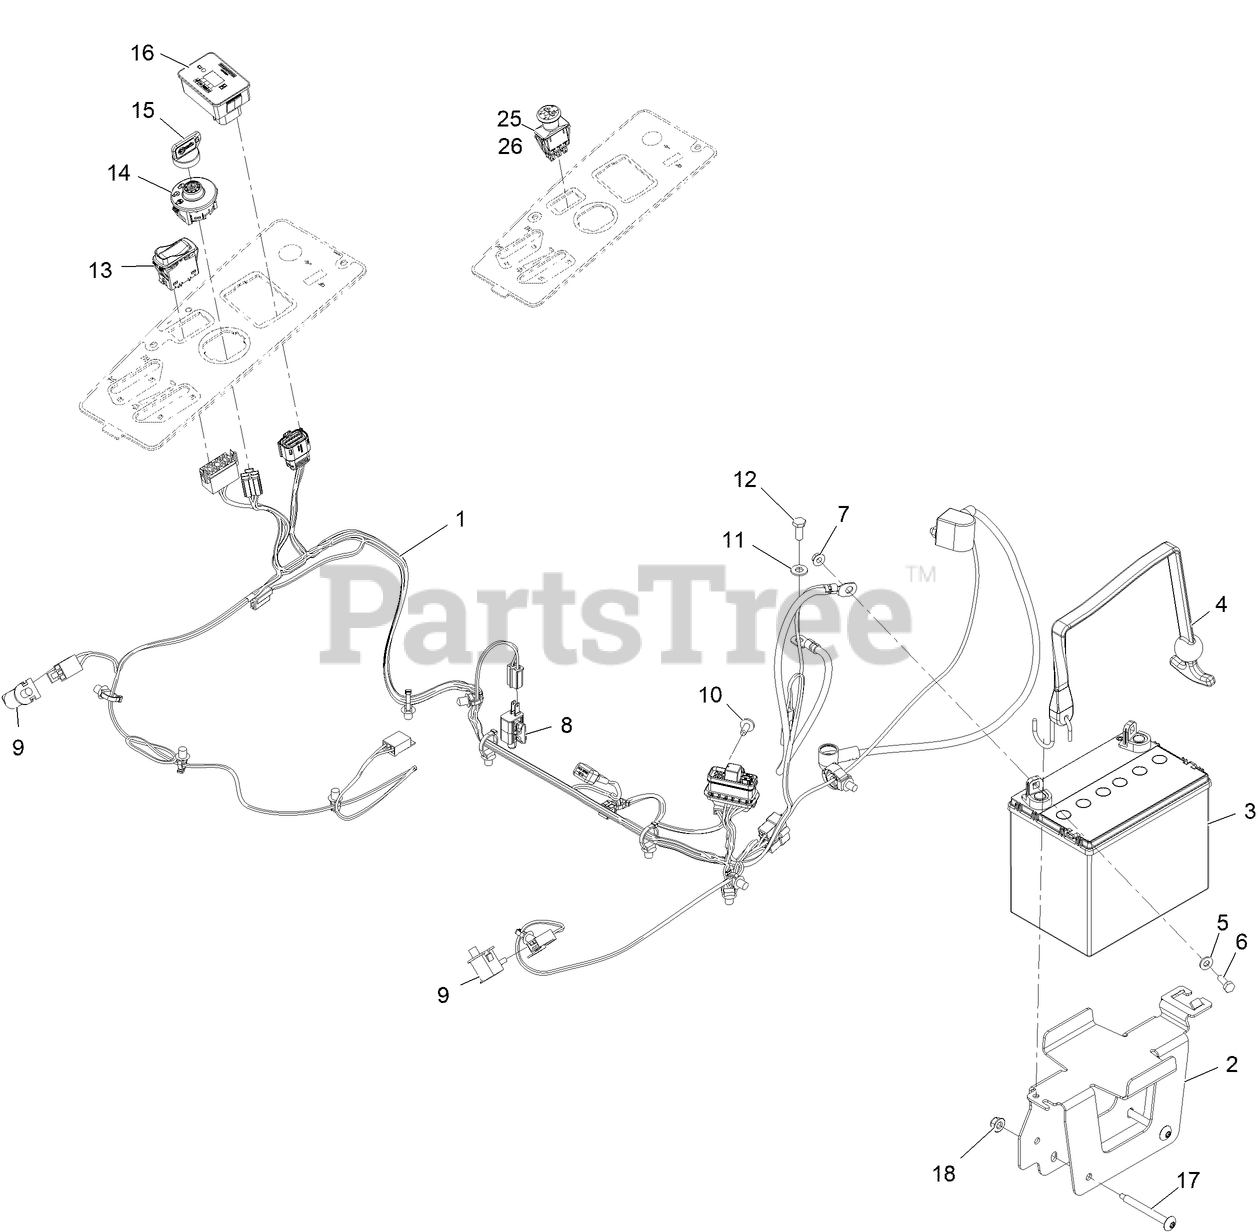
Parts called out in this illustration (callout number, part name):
1	Harness-Main
2	TRAY-BATTERY
3	Battery
4	STRAP, BUNGEE
5	WASHER-FLAT
6	SCREW-HH
9	SWITCH-BAIL
10	SCREW-TORX
11	WASHER-PLAIN
12	SCREW-HH
13	SWITCH-ROCKER, ON-NONE-ON
14	SWITCH-IGNITION
15	KEYS-IGNITION (SPARE PAIR
15	KEY-IGNITION
16	MODULE ASM
17	SCREW-TORX
18	NUT-HF, NI
25	SWITCH-PTO
